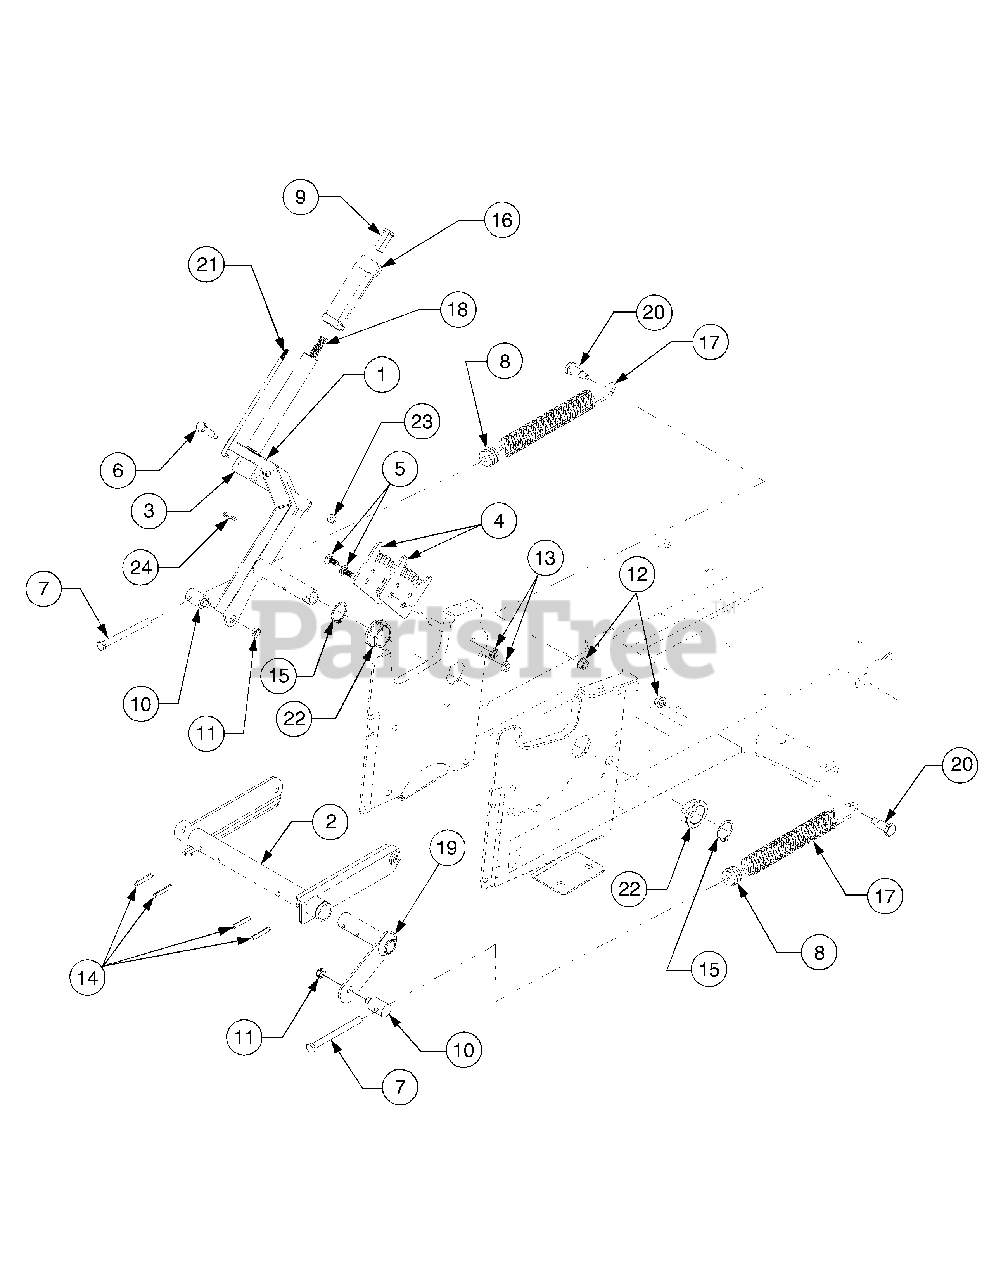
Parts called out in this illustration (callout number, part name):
5	Bolt, Carriage, 5/16-18 x .75
6	Screw, Shoulder, .374 x 1.375
7	Screw, Hex Cap, 3/8-16 x 4.25 GR5
8	Insert, Spring
9	Button, Handle
10	Ferrule, Adjustment
11	Nut, Hex Center Lock, Jam, 3/8-24
12	Nut, Hex Flanged Lock, 3/8-16
13	Nut, Hex Flanged Top Lock, 5/16-18
14	Pin, Spiral Spring, 1/4 Dia x 1.5
15	Ring, Snap, 1.25 Dia Shaft
16	Grip, Lift Handle
17	Spring, Extension
18	Spring, Compression
20	Bolt, Shoulder
21	Rod, Index
22	Bearing, Hex Flange, 1.25 ID
23	Nut, Hex Flange Lock, 1/4-20
24	Pin, Internal Cotter
